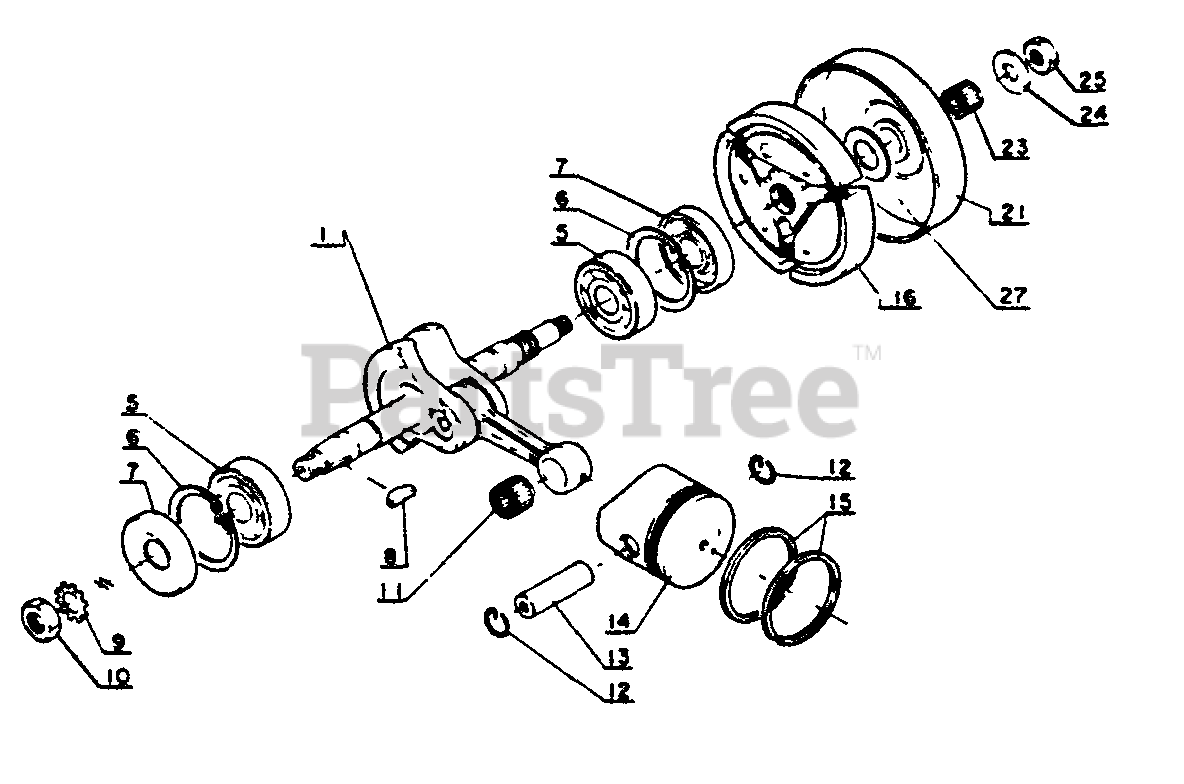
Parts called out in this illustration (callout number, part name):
1	CRANKSHAFT ASSY
5	BEARING, BALL - 6201
6	RING, RETAINING - 32
7	SEAL, OIL
9	LOCKWASHER - 8
11	BEARING, NEEDLE
12	RING, RETAINING
13	PIN, PISTON
15	RING, PISTON
16	CLUTCH ASSY
16	SPRING, CLUTCH
16	SHOE, CLUTCH
16	HUB, CLUTCH
16	PLATE, CLUTCH
16	RIVET
21	CASE, CLUTCH
23	BEARING, NEEDLE
24	WASHER, CLUTCH
25	LOCKNUT - 6
27	WASHER, CLUTCH
